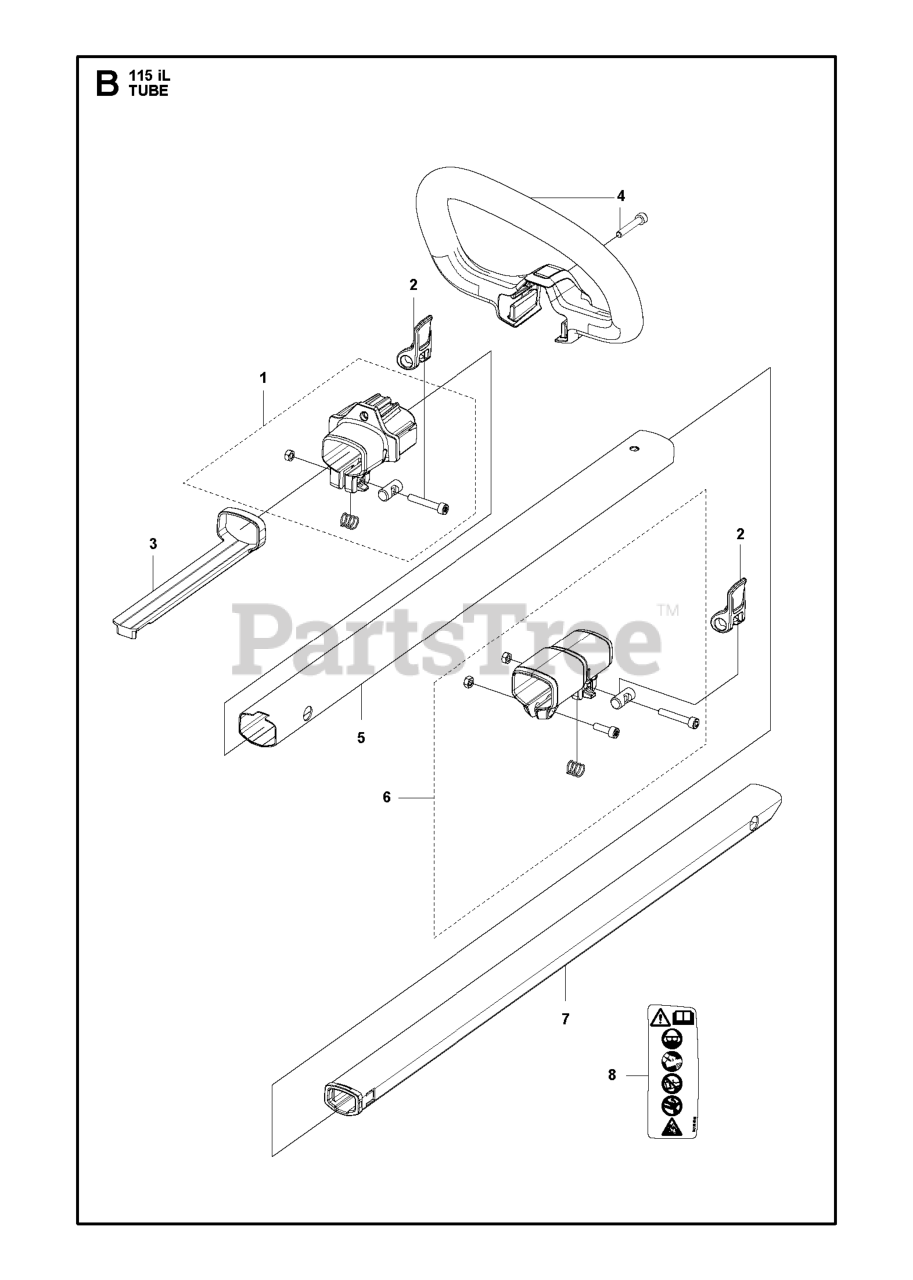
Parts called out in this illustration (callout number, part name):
1	COUPLING ,FRONT HANDLE ASSY
3	SPACER FRONT HANDLE
4	HANDLE ,FRONT HANDLE ASSY
6	COUPLING ,TUBE COUPLING ASSY
7	TUBE ASSY SMALL TUBE ASSEMBLY
